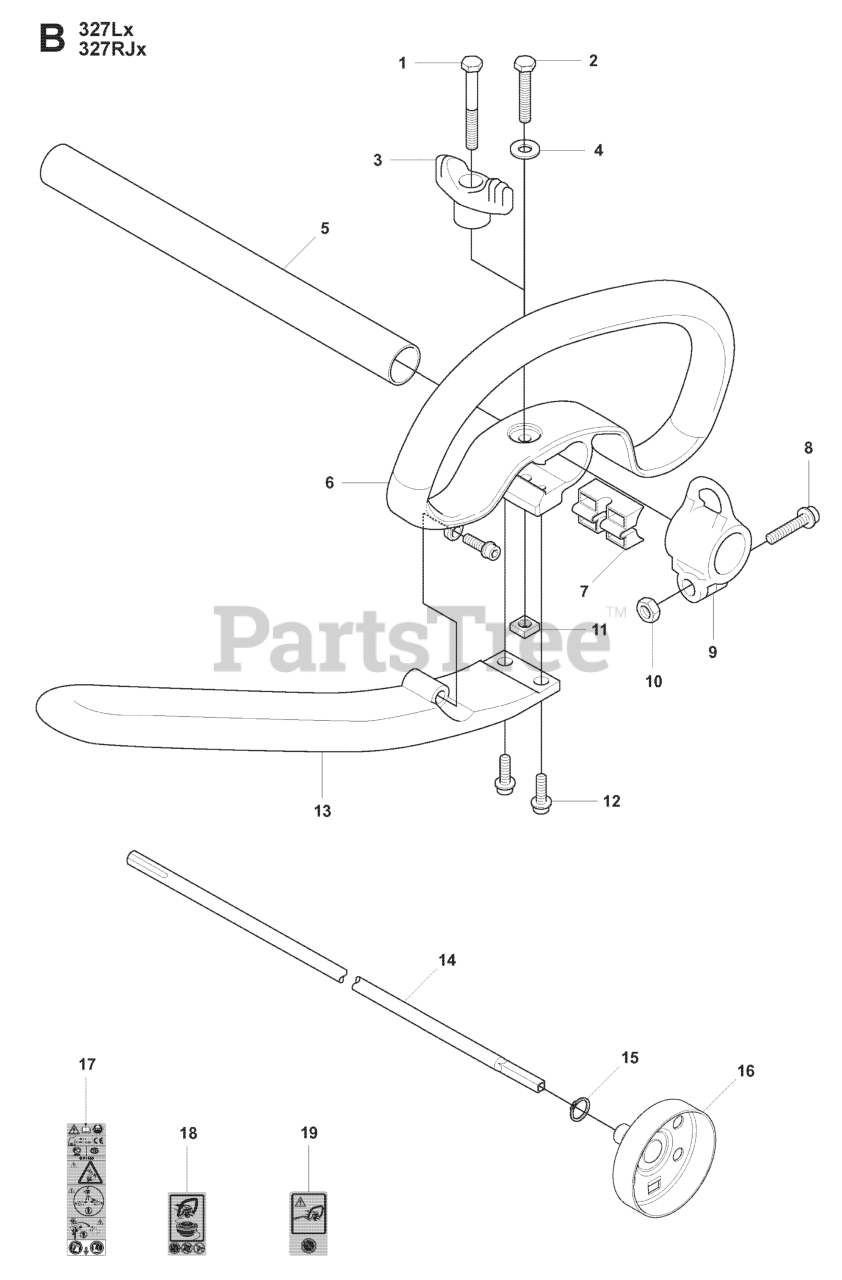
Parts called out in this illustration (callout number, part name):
1	SCREW M6X50
5	DRIVE TUBE ASSEMBLY
6	RP HANDLE, LOOP
6	HANDLE, LOOP
7	SPACER PLASTIC
8	SCREW
9	HARNESS HOLDER
13	HANDLE EXTENSION
14	DRIVE SHAFT
15	RETAINING RING SGA 10
16	CLUTCH DRUM
17	RP WARNING DECAL
18	DECAL WARNING "NO BLADES"
